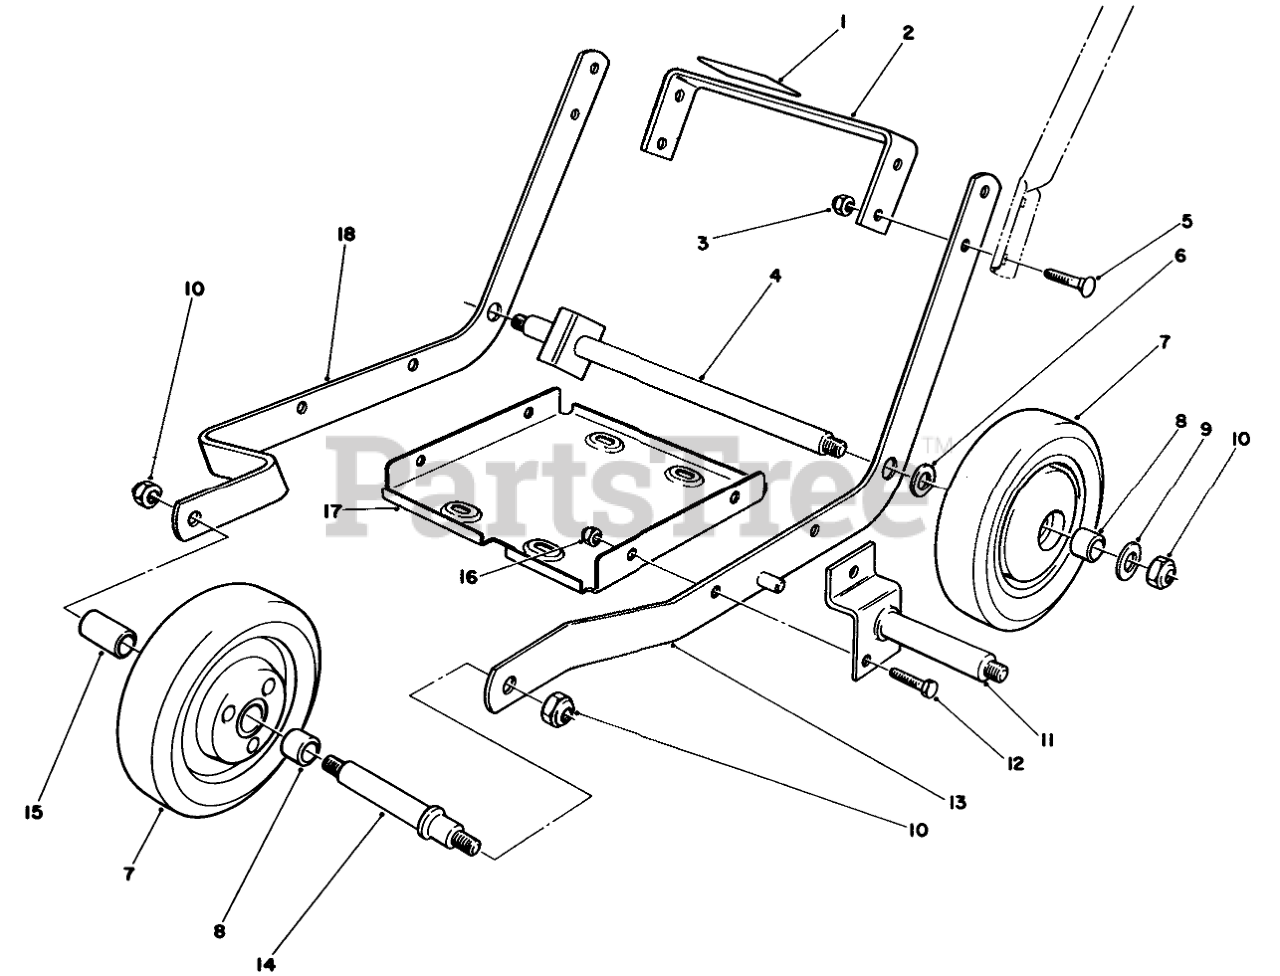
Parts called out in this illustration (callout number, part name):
1	Decal-Warning
2	Plate-Escutcheon
3	NUT-LOCK, NI
4	AXLE CLAMP WA
5	SCREW-CARR
6	WASHER-PLAIN
7	Wheel & Tire Assembly (Incl. Ref. #8)
8	BUSHING
9	WASHER
10	NUT-LOCK, NI
11	Pivot Pin Assembly
12	SCREW-HH
13	Frame-L.H.
14	FRONT AXLE (2 HP)
15	SPACER
16	NUT-LOCK, NI
17	Plate-Engine
18	Frame-R.H.
